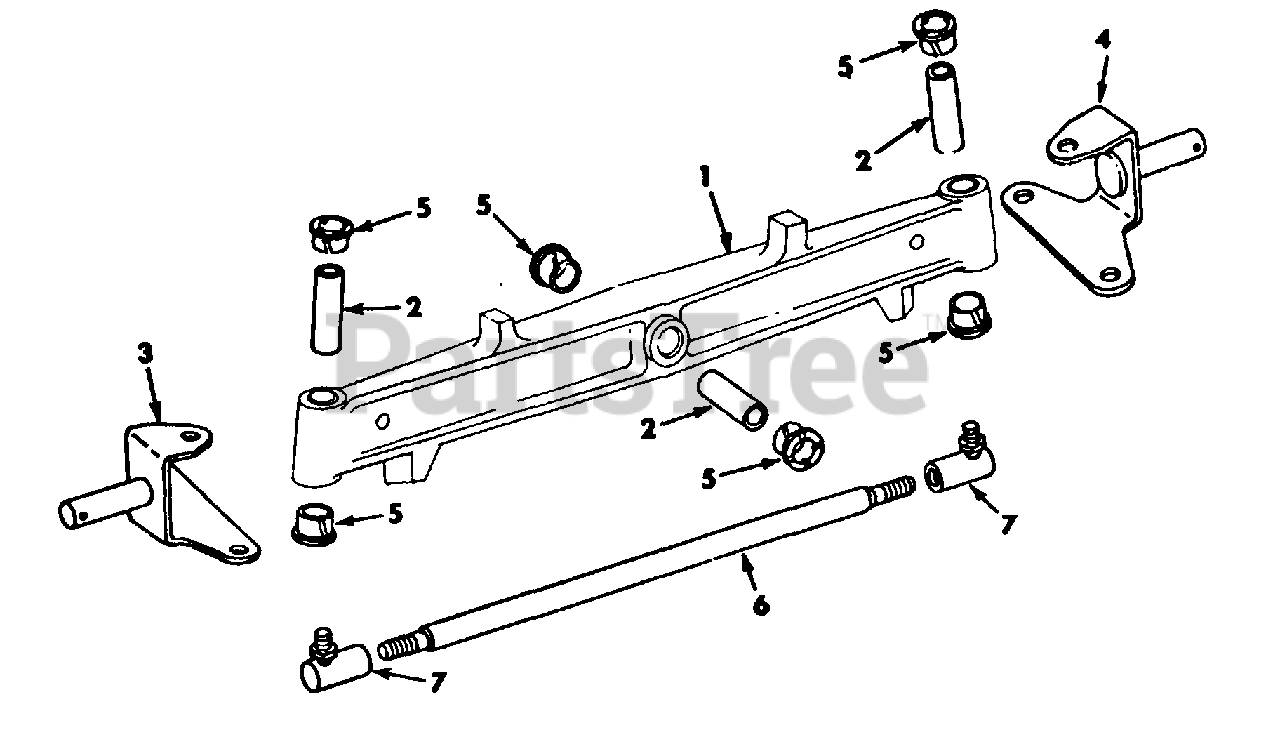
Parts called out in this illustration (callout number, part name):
1	AXLE, FRONT
2	BUSHING, FRONT AXLE
3	ARM ASSY, SPINDLE RH
4	ARM ASSY, SPINDLE LH
5	BEARING, FRONT AXLE
7	JOINT, TIE ROD
